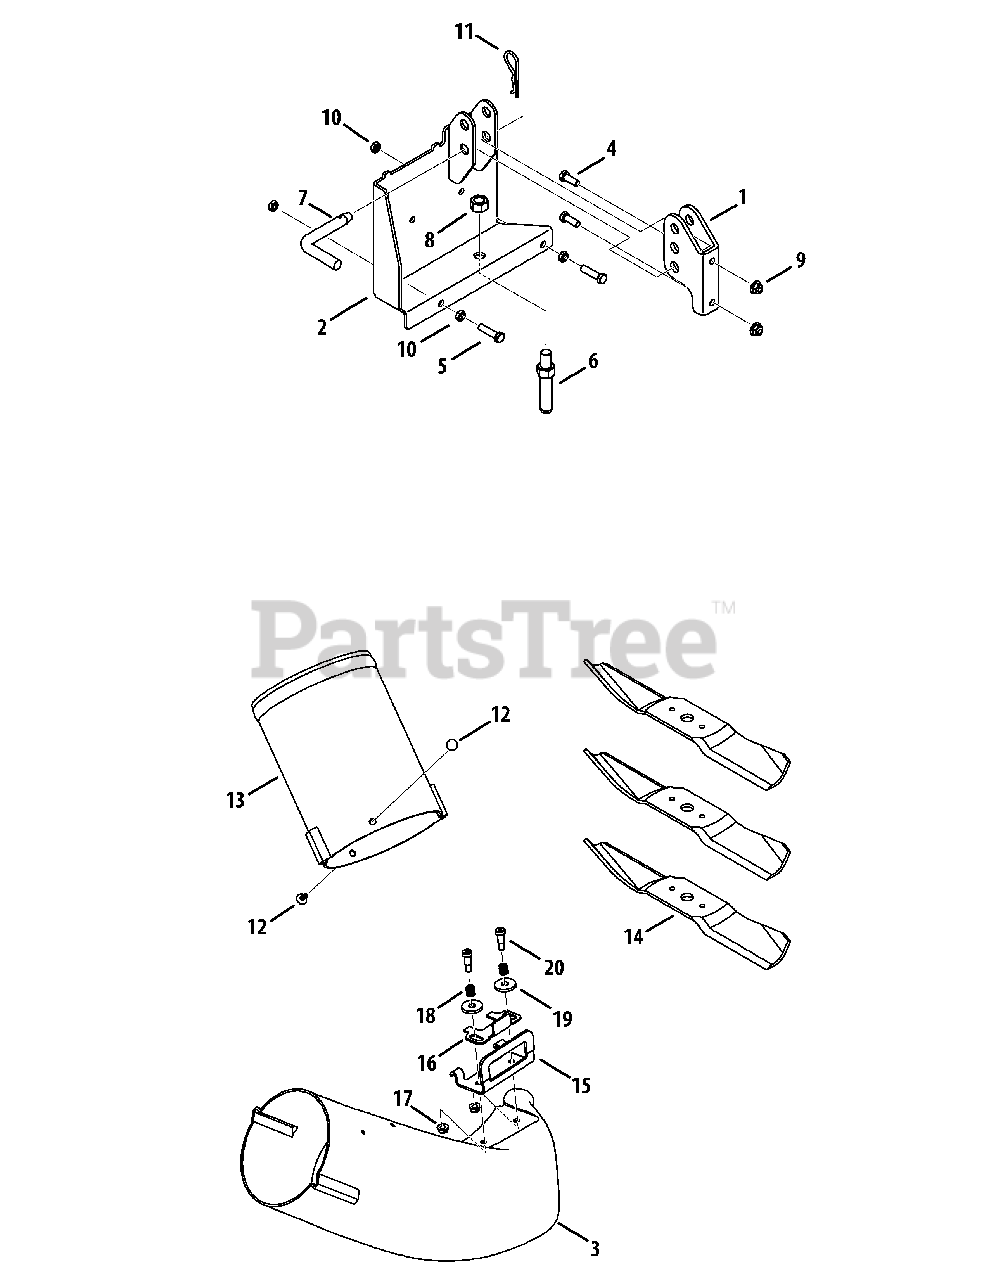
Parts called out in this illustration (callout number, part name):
1	Hitch Bracket
2	Bagger Mounting Assembly
3	Chute Discharge Elbow, 44" Deck
4	Hex Head Screw, 3/8-16 x 1.00
5	Hex Head Screw, 3/8-16 x 1.50
6	Catcher Adapter Stud
7	Clevis Pin, R-Angle
8	Hex Nut, 5/8-18
9	Flange Lock Nut, 3/8-16
10	Jam Nut, 3/8-16
11	Internal Cotter Pin, .148 x 3.00
12	Ratchet Clip
13	Bagger Chute Adapter
14	Blades, 15.94 x 2.5 x .2
15	Chute Bracket, 44" Deck
16	Bag Latch
17	Flange Lock Nut, 5/16-18
18	Compression Spring, .50 OD x .50 Lg.
19	Flat Washer, .406 x 1.25 x .157
20	Shoulder Screw, 3/8 x .625; 5/16-18
